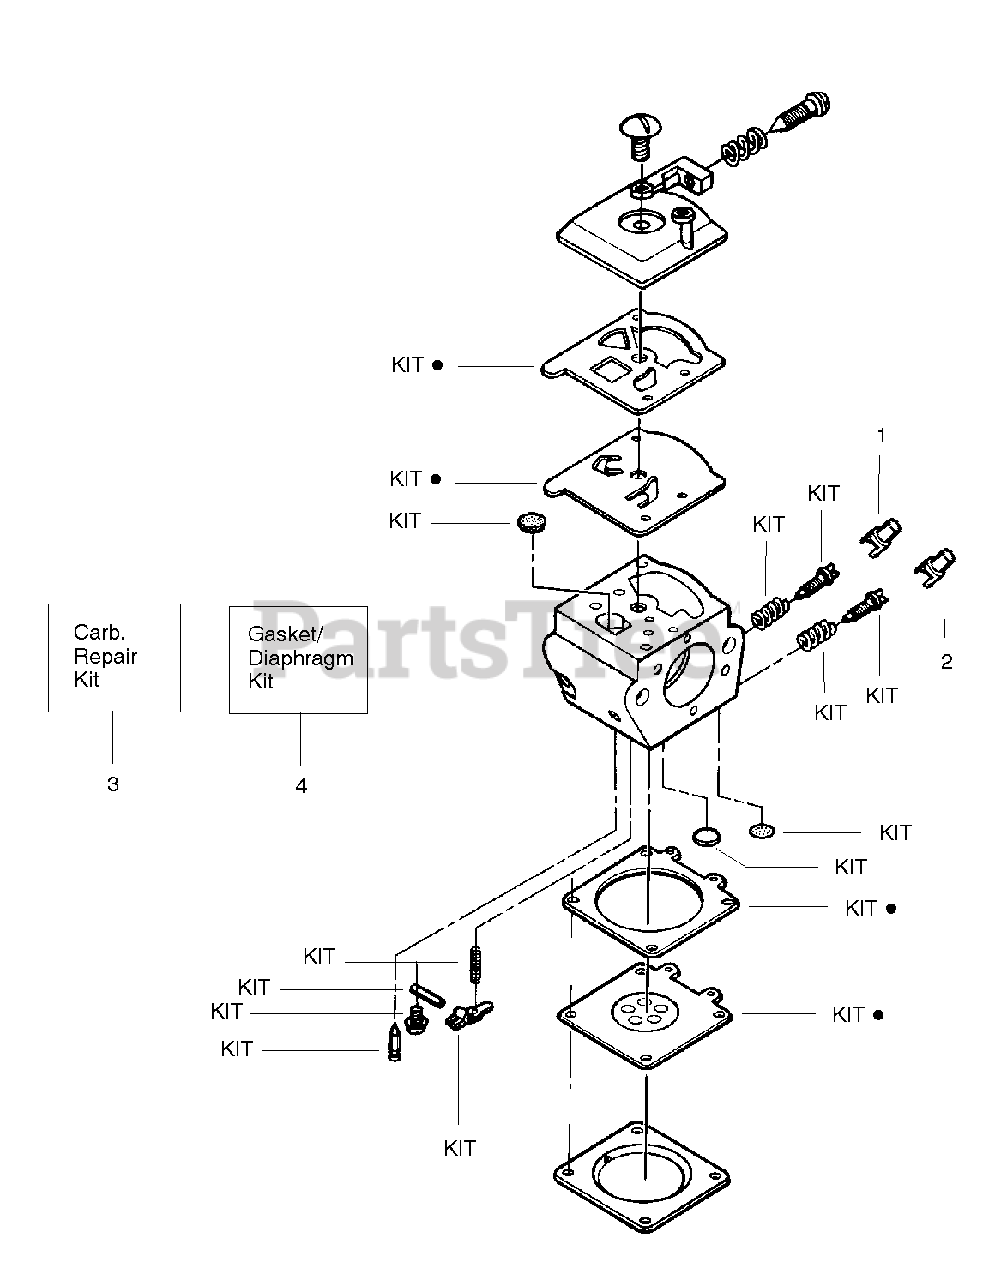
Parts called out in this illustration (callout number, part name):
1	Limiter Cap-High
2	Limiter Cap-Low
3	Carburetor Repair Kit
4	Gasket/Diaphragm Kit
